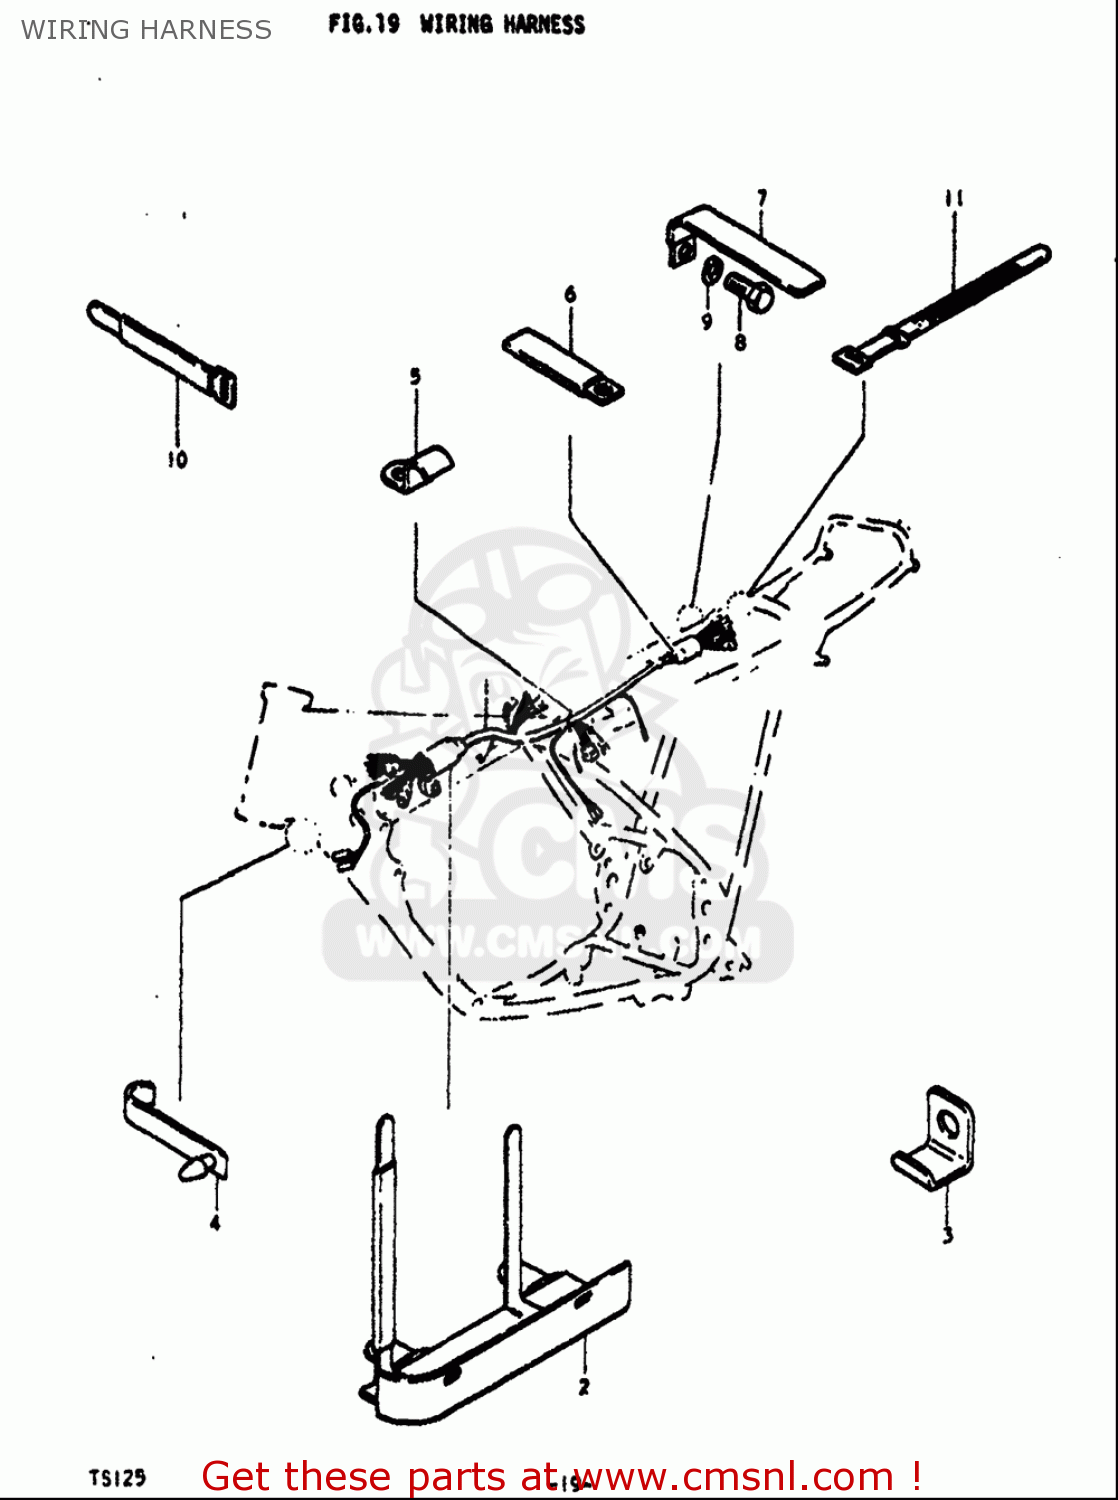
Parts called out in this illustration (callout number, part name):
6	CLAMP
8	BOLT
9	WASHER,LOCK
10	CLAMP
11	CLAMP(L:120)
